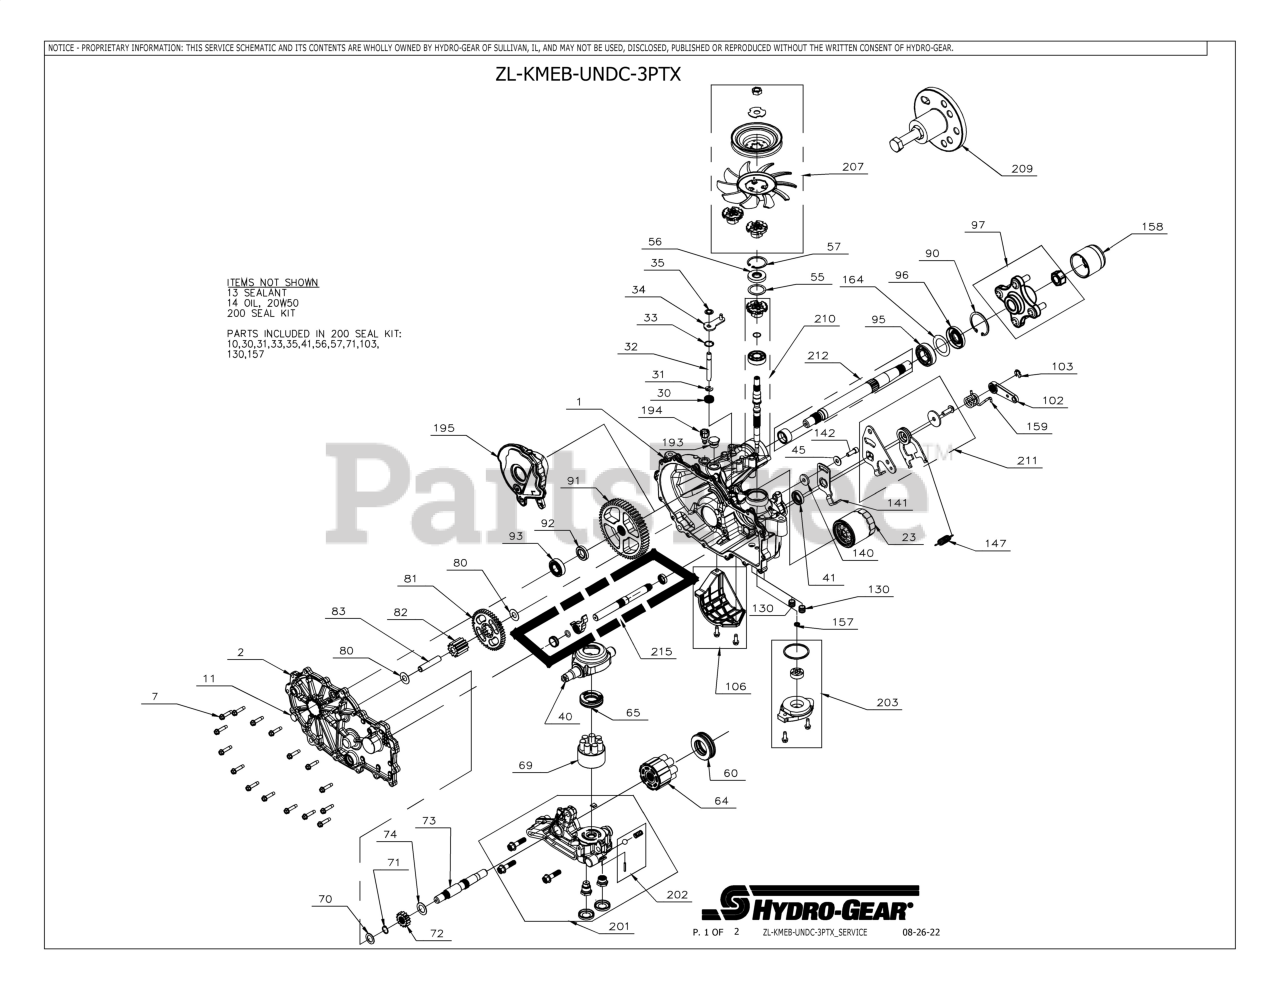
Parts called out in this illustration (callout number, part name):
1	KIT, HOUSING, MAIN, LH, CHRG, CNTL
2	KIT, SIDE COVER, LH
7	SCREW,HEX WASHER 1/4-20X1.125
11	PLUG EXT HEX VENT 9/16 18
13	SEALANT TUBE 10.1OZ.
14	FLUID, HYDRO 15W50 QT
14	FLUID, HYDRO 20W50 QT
23	FILTER, HYDRO-GEAR 2800 TRANS
30	Seal, lip .375 x 375 x 325
31	RING. RETAINING
32	ROD, BYPASS
33	RING, RET .750
34	HG BYPASS ARM (52370)
35	RING, RTNG .
40	TRUNNION, SWASHPLATE
41	SEAL, LIP 18X32X7
55	WASHER 1.23X1.56X.04
56	SEAL, LIP 17 X 40 X 7 HNBR
57	RING, RET 1.56 INT
60	HG THRUST BEARING (51462)
64	HG 16CC CYLINDER BLOCK (71579)
65	BEARING. THRUST 30 X 52 X 13
69	ASSY, BLOCK 7 PISTON
70	WASHER .63X1.0X.05
71	RING, RET 62 EXT
72	GEAR 14T STEEL
73	SHAFT, MOTOR
74	WASHER .71 X 1.16 X .04
80	WASHER .5X1.0X.032
81	GEAR 45 TOOTH
83	GEAR 11 TOOTH STEEL
90	RING, RETAINING
91	GEAR 54 TOOTH
92	SPACER
93	KIT, BEARING
95	BEARING, BALL 25.4 X 52 X 15
96	SEAL, LIP
97	KIT, HUB 4 BOLT
102	HANDLE- ACTUATING
103	CLIP,BRAKE ARM HYDROGEAR 52027
106	KIT, FILTER GUARD
130	TUBE CHARGE TRIPLE ORING
141	ARM, NEUTRAL LEFT
142	SHCS 5/16-24X1 PATCH
147	SPRING, EXTENSION
157	KIT GEROTOR SEAL
158	CAP, AXLE
159	SPRING, TORSION CCW
164	WASHER, 1.355 x 2.035 x .021 FLAT
194	ASSEMBLY, FITTING 9/16-18 BREATHER
195	ASSEMBLY, TANK, EXPANSION, INTERNAL, LH
200	KIT, SEAL
201	KIT, CENTER SECTION, LH, CHARGE
202	KIT CHARGE RELIEF
203	KIT, CHARGE
207	KIT- FAN/PULLEY
209	HUB PULLER 5 BLT
210	KIT INPUT SHAFT
211	RING, RTNG .
212	KIT SHAFT AXLE
215	KIT, OUTBOARD, RH ROT A / LH ROT B
